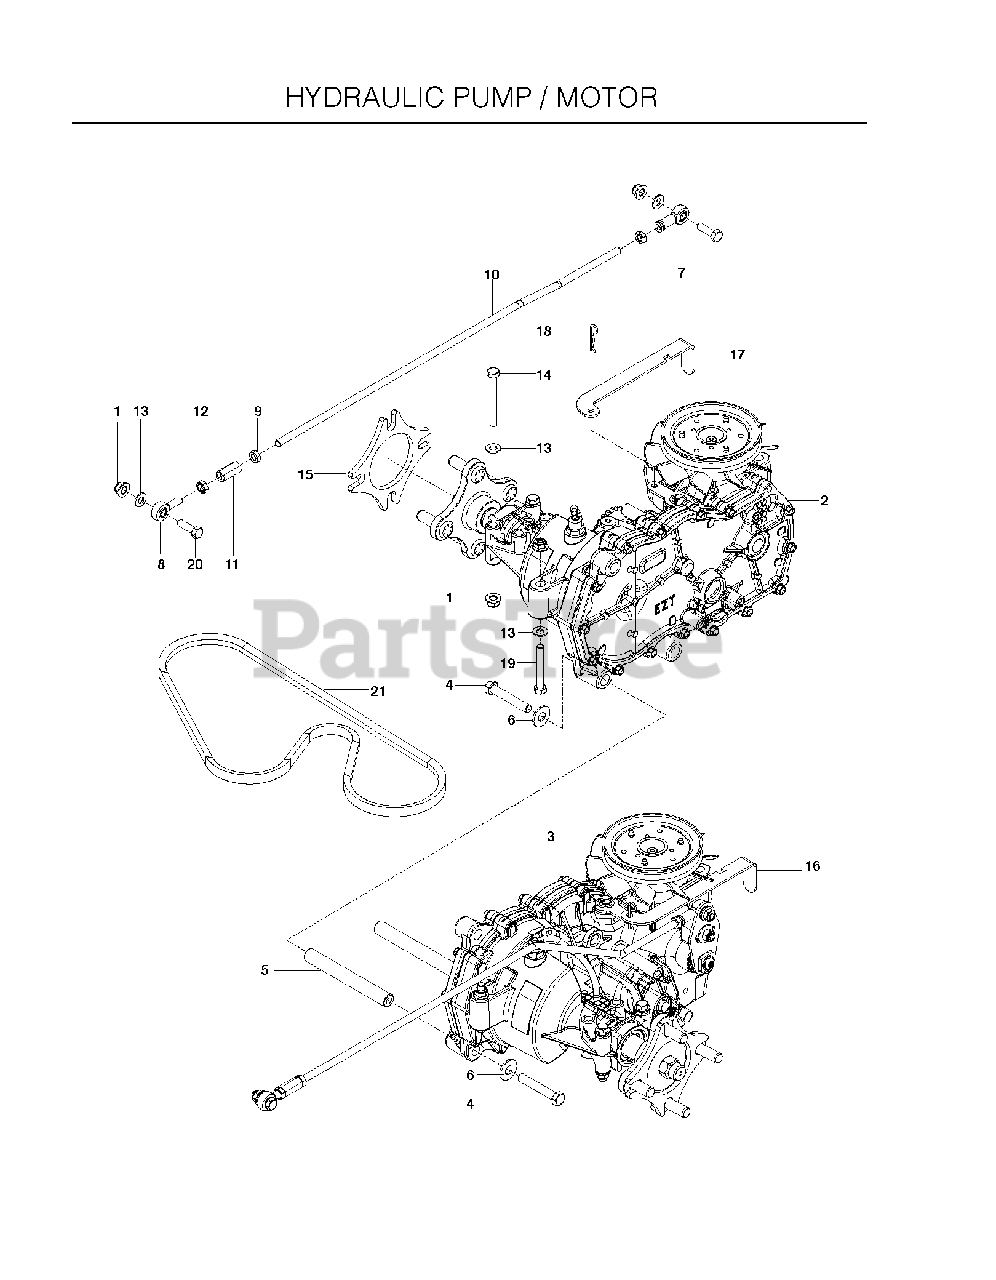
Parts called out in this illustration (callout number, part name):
1	5/16-18 NYLOC FLANGE NUT
2	HG_HYDRO RH
3	HG_HYDRO LH
4	HCS 3/8C X 2 1/4
5	HYDRO SPACER
6	WASHER 3/8 FLAT
7	RH ROD END
8	ROD.END.LH
9	NUT 5/16-24 UNF HEX JAM
10	CONTROL ROD
11	ROD END COUPLER
12	NUT 5/16F LEFTHAND
13	FLAT WASHER 5/16 SAE
14	HCS 5/16C X 2-3/4
15	SPACER, WHEEL
16	RELEASE LEVER LH
17	RELEASE LEVER RH
18	HAIRPIN #2
19	CAPSCREW
20	HCS 5/16C X 1
21	BELT 30 ZEZT
